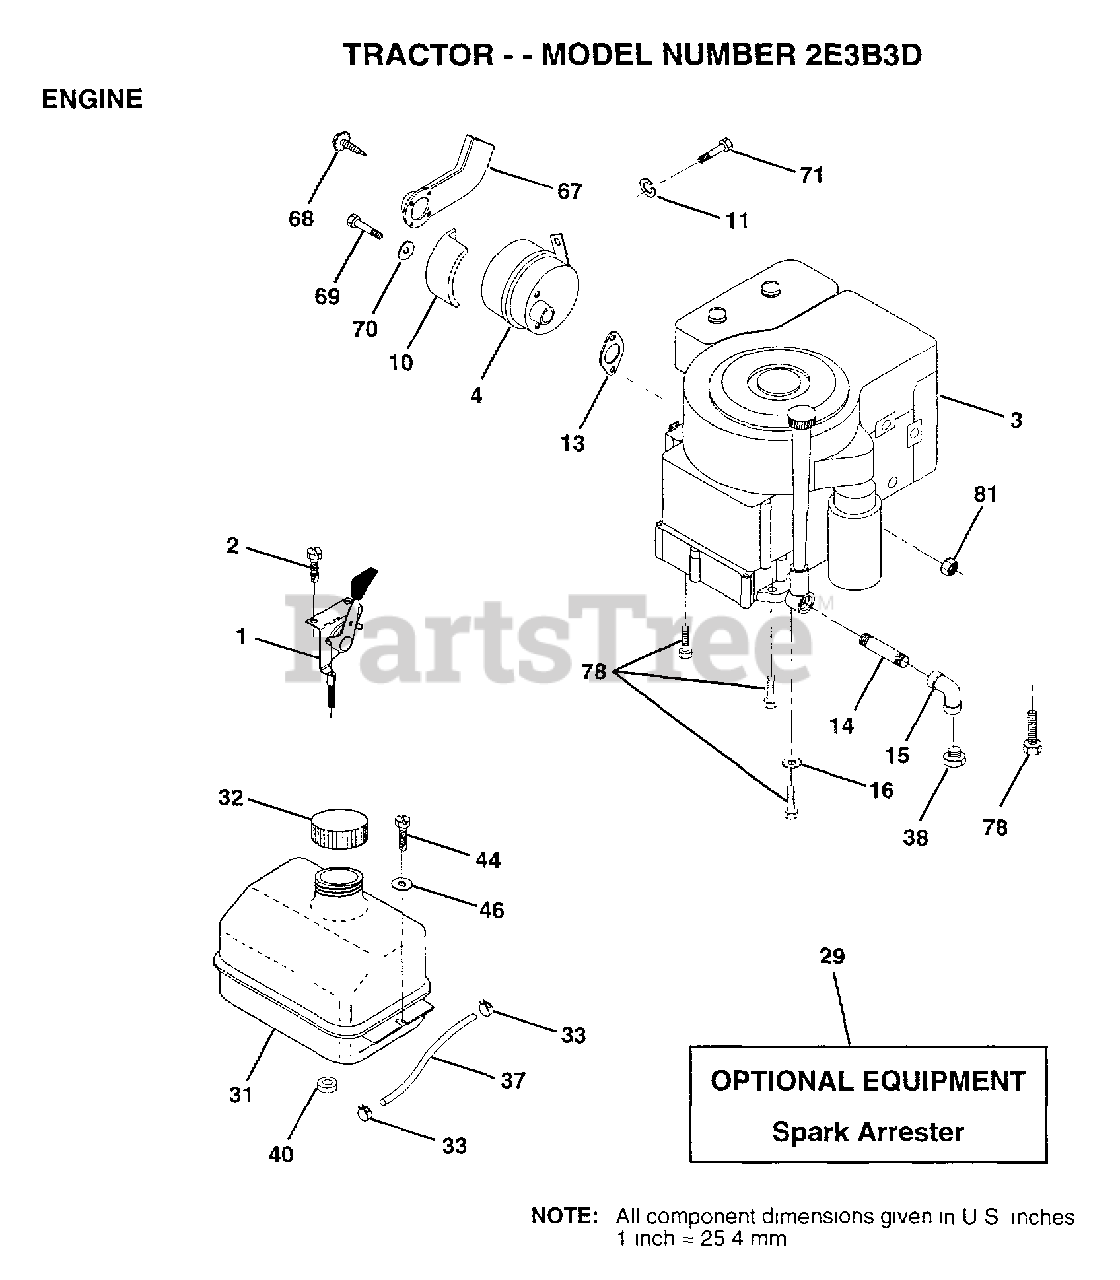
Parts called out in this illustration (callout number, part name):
1	THROTTLE CONTROL
2	SCREW LT
4	MUFFLER LTV
10	SHIELD HEAT LTV
13	GASKET ENG 1 313 LD TIN PLATED
14	PIPE NIPPLE
15	ELBOW
16	LOCKWASHER
31	TANK.FUEL.LT.
32	CAP ASM FUEL
33	HOSE CLAMP
37	LINE FUEL
44	SCREW HEX CRT
46	WASHER
67	DEFLECTOR MUFFLER
69	"BOLT,HEX"
70	WASHER T
78	SCREW
81	NUT
